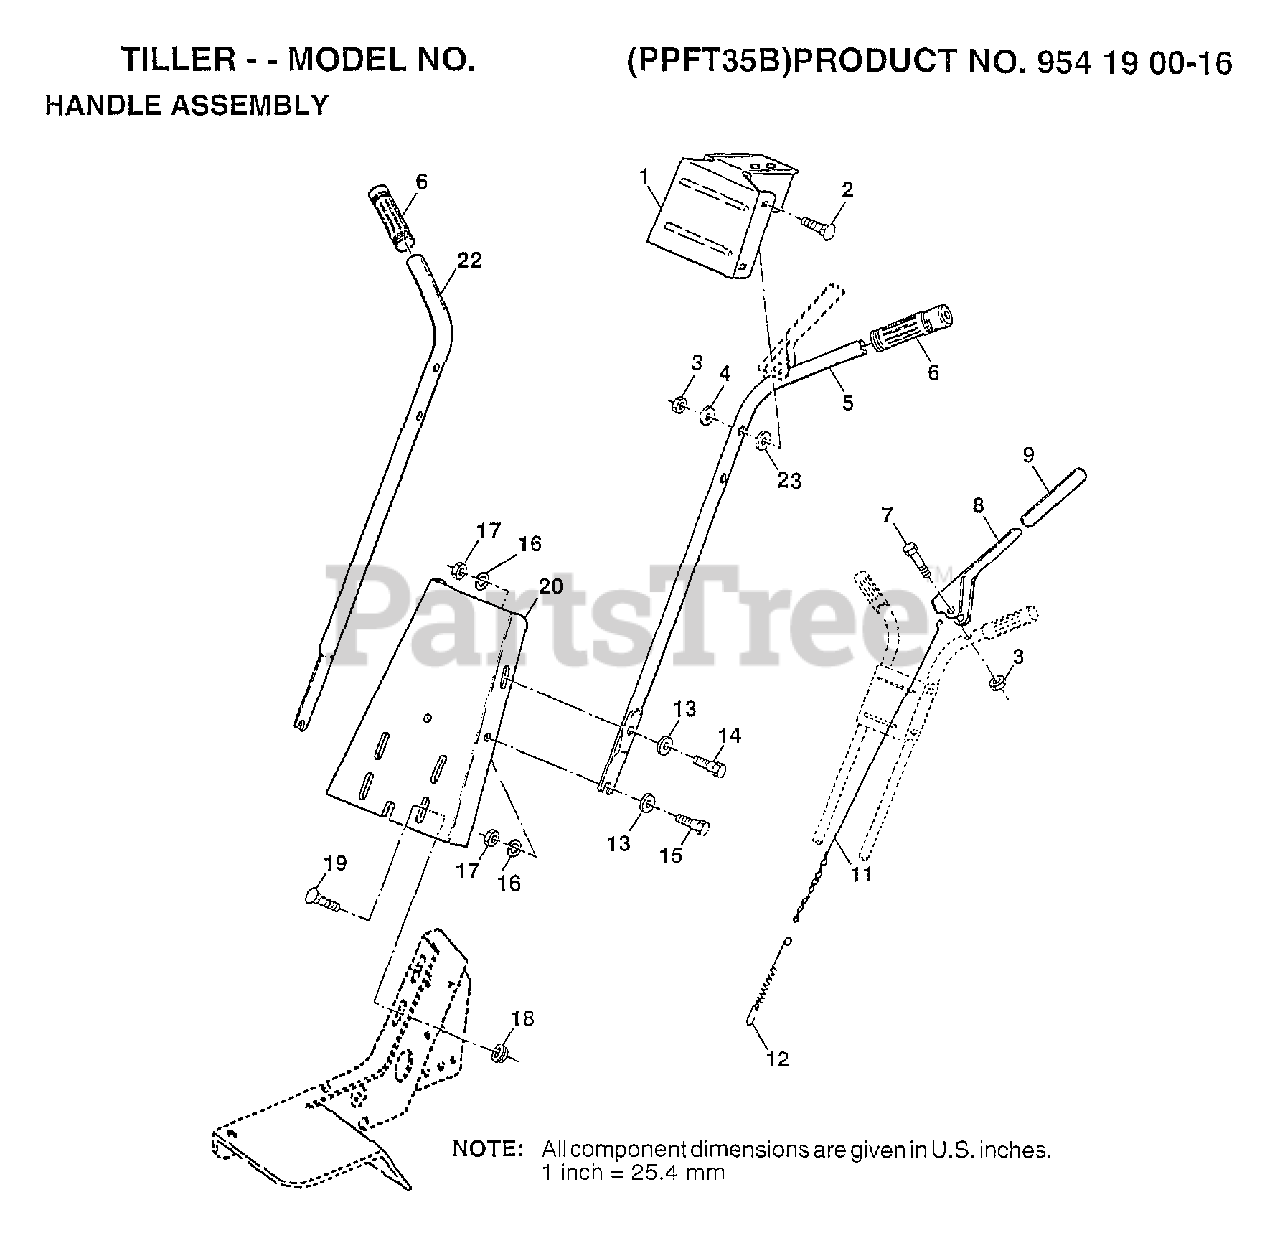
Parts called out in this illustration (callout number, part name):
1	HANDLE BRKT
2	BOLT
4	WASHER
5	HANDLE LH
7	BOLT.HEX.5/16-1.5
9	GRIP T
12	SPRING EXT TI
13	WASHER
15	BOLT
16	LOCKWASHER
17	NUT.HEX.5/16-18
18	NUT
19	BOLT
20	PANEL. HANDLE
22	HANDLE RH
23	WASHER
